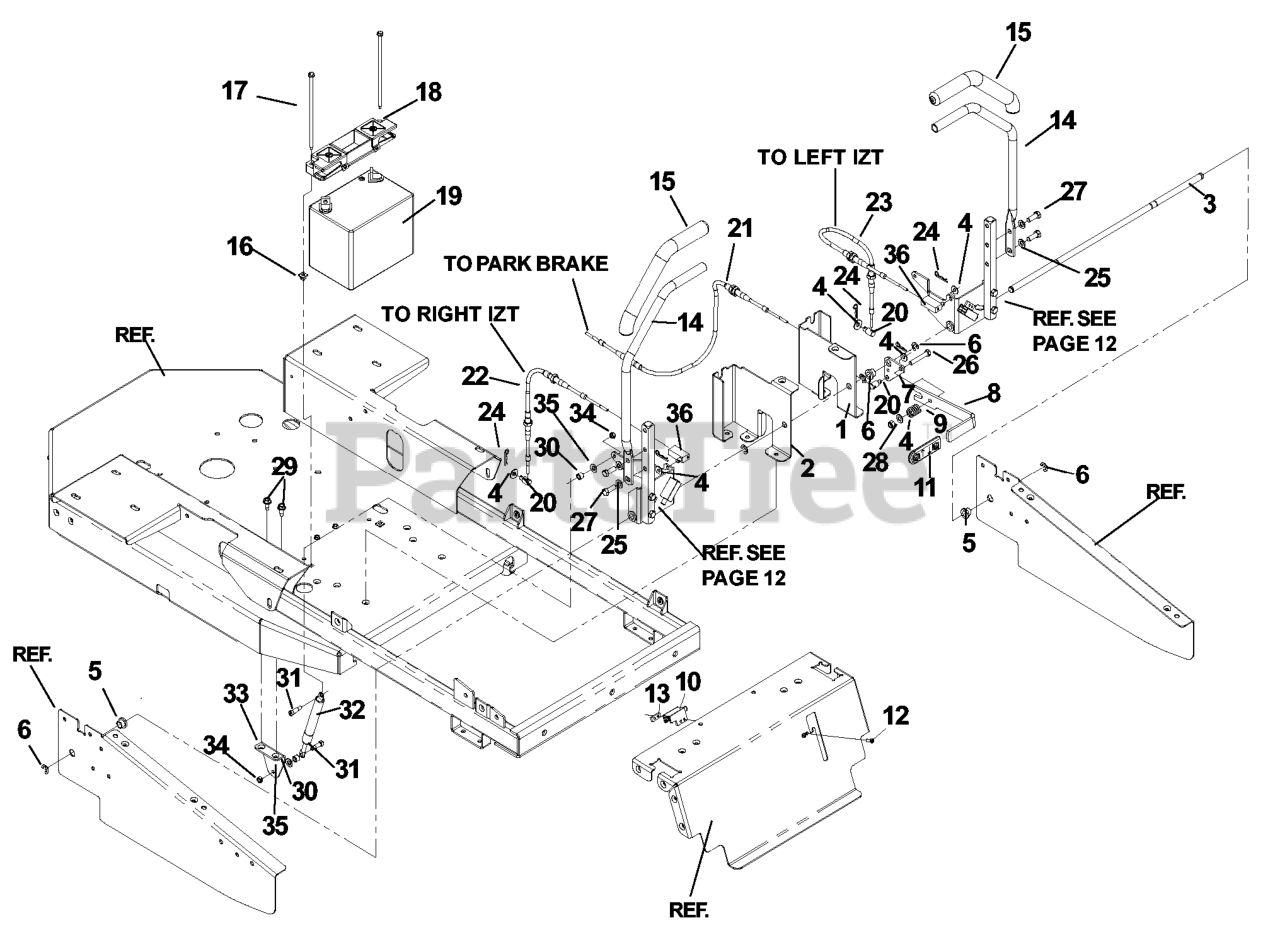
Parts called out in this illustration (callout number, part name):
1	BATTERY SUPPORT-LH
2	BATTERY SUPPORT-RH
3	CONTROL PIVOT SHAFT
4	WASHER 5/16 FLAT
5	BUSHING, FLANGED NYLON
6	E-RING 1/2 (2 2)
7	BRAKE LEVER
8	UPPER BRAKE LEVER
9	COMPRESSION SPRING
10	SWITCH, INTERLOCK
11	GRIP, PARK BRAKE
12	SCREW #10-24 X 5/8
13	TAPPED PLATE
14	CONTROL LEVER-BLACK
16	PUSH NUT-NYLON
17	BOLT - 1/4-20 X 7.5
18	BATTERY HOLD DOWN
19	BATTERY, 12 V 330 AMP
20	CONTROL SWIVEL
21	BRAKE CABLE
22	CABLE-RH
23	CABLE-LH
24	HAIRPIN #2
25	WASHER, 3/8 DISC SPRING SPEC
26	HCS 5/16-18X2
27	HCS 3/8-16X1.GRD.5.ZD
28	NUT 5/16 NYLOC
29	BOLT 5/16-18 X 3/4
31	SCREW, 5/16 X 5/8 SHOULDER
33	DAMPENER BRACKET
34	JAM NUT 1/4C (2 2 PW01)
36	UPPER CABLE END
